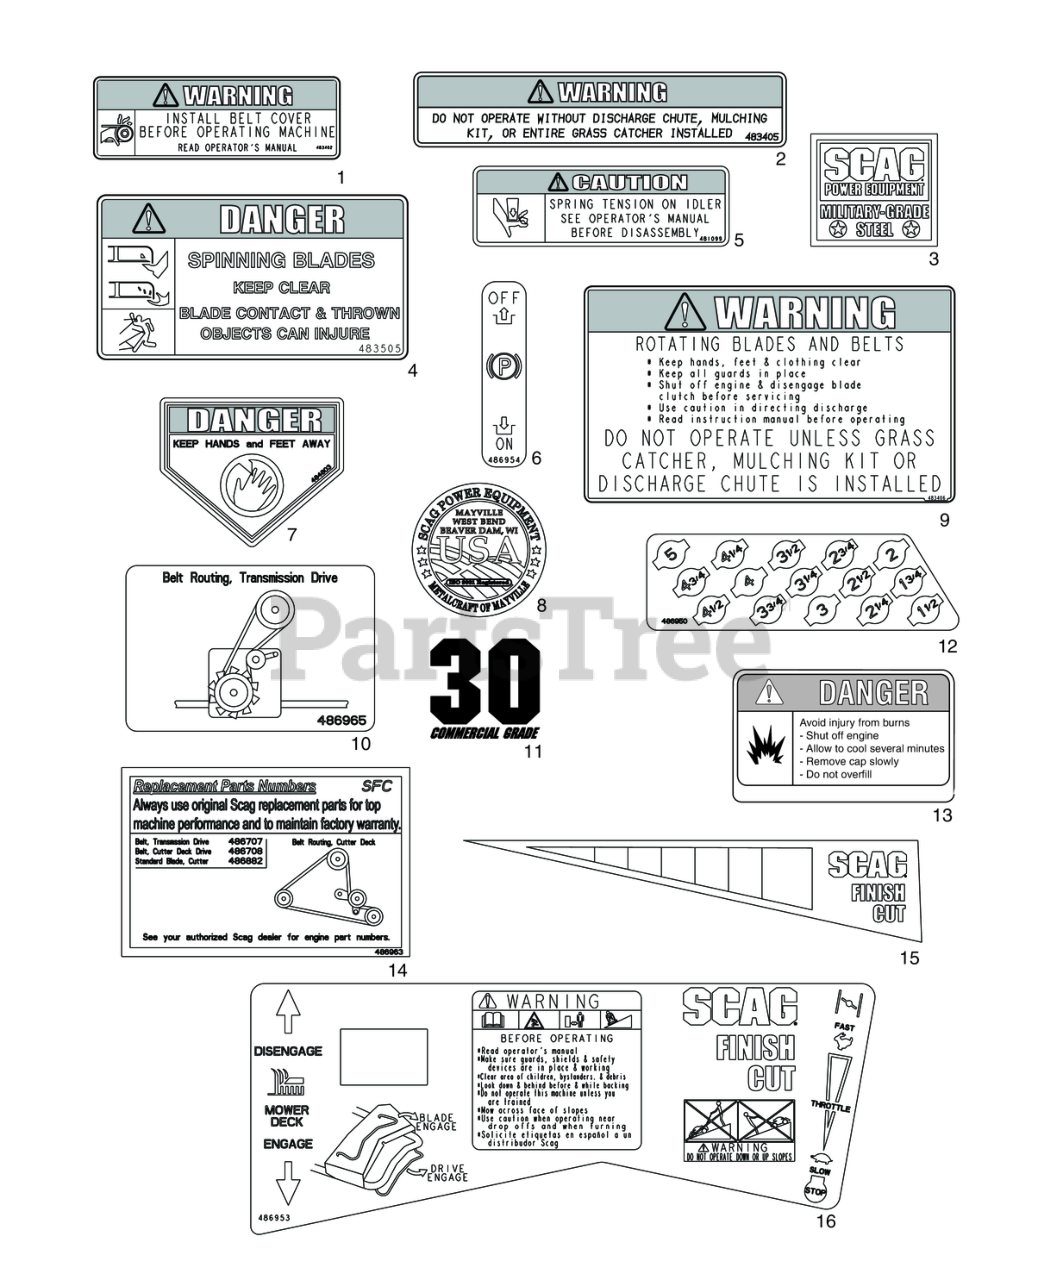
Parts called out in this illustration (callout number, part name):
1	Decal, Warning - Belt Cover
2	Decal, Warning-Discharge
3	Decal, Military Grade
4	Decal, Spinning Blades
5	DECAL, SPRING LOADED IDLER
6	Decal, Parking Brake
7	Decal, Danger - Cut Finger
8	Decal, Metalcraft - USA
9	Decal, Warning - Rotating Blades
10	Decal, Belt Routing
11	Decal, 30 Commercial Grade
12	Decal, Cut Height
13	Decal, Fuel Tank
14	Decal, Replacement Parts
15	Decal, Belt Cover
16	Decal, Instrument Panel
